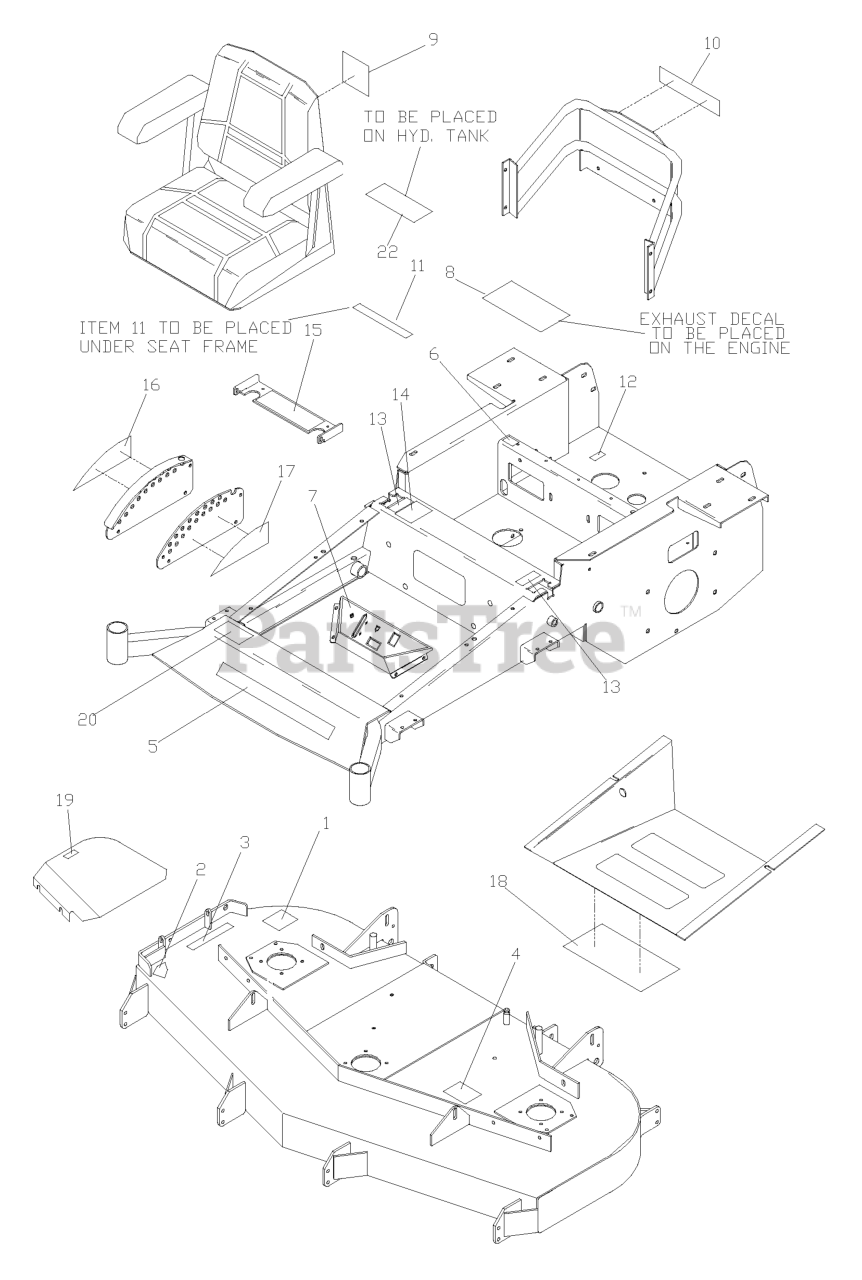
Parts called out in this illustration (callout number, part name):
1	DECAL, ANTI SCALP
2	DECAL, DANGER
3	DECAL, CPSC
4	DECAL, BELT ROUTING
5	DECAL, HUSQVARNA 17.5"
6	DECAL, FUEL VALVE
7	DECAL, CONSOLE
8	DECAL, EXHAUST
9	DECAL, CROWN H
10	DECAL, HUSQVARNA LOGO 9.25"
11	DECAL, BATTERY
12	DECAL, PROP. 65
13	DECAL, MOTION CONTROL
14	DECAL,THROWN OBJECT
15	DECAL, WARNING
16	DECAL, HEIGHT
17	DECAL, HEIGHT
18	DECAL, SERVICE
19	DECAL, NO STEP
20	DECAL, NASCAR
21	DECAL, 5223
21	DECAL 5223L
21	DECAL 5225
21	DECAL 6125
22	DECAL, MOBIL 1
